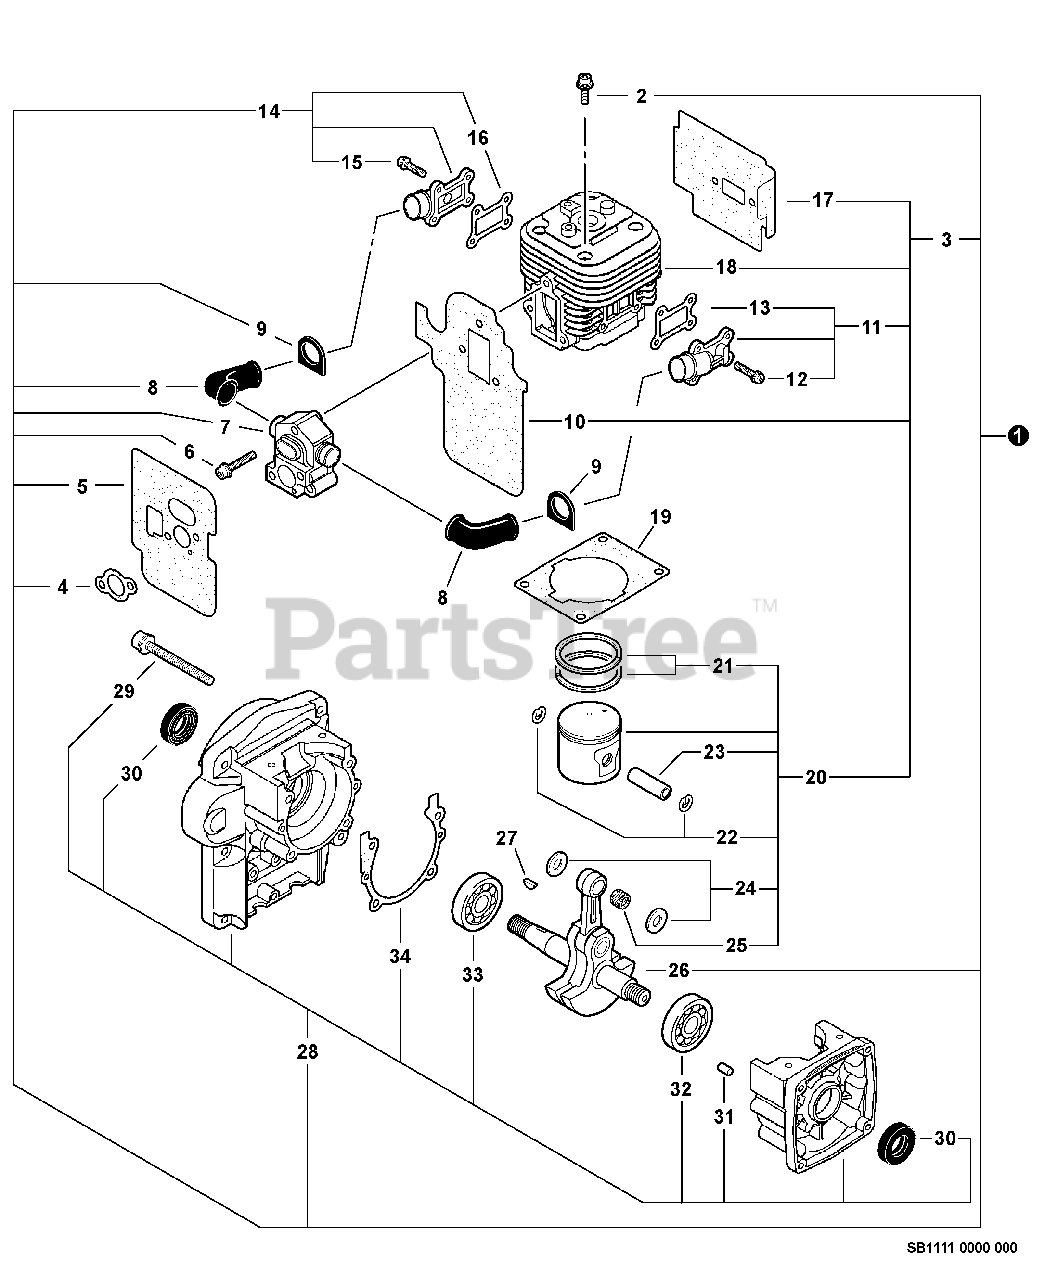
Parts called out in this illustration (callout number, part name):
1	SHORT BLOCK -- SB1111
2	SCREW - 5X22
3	CYLINDER/PISTON KIT
4	GASKET, INTAKE
5	SHIELD, INTAKE
6	SCREW - 5X35
7	VALVE ASSY
8	HOSE, AIR
9	GROMMET
10	GASKET, INTAKE
11	REED VALVE KIT - OUTER
12	SCREW - 4
13	GASKET, INTAKE
14	REED VALVE KIT - INNER
15	SCREW - 4
16	GASKET, INTAKE
17	SHIELD, EXHAUST
18	CYLINDER
19	GASKET, CYLINDER
20	PISTON KIT
21	RING, PISTON
22	RING, RETAINING - 8
23	PIN, PISTON
24	WASHER - 10
25	BEARING, NEEDLE - 10
26	CRANKSHAFT ASSY
27	KEY - 3X14
28	CRANKCASE KIT
29	SCREW - 5X40
30	SEAL, OIL
31	PIN - LOCATING
32	BEARING, BALL - 6202
33	BEARING, BALL - 6302C3
34	GASKET, CRANKCASE
